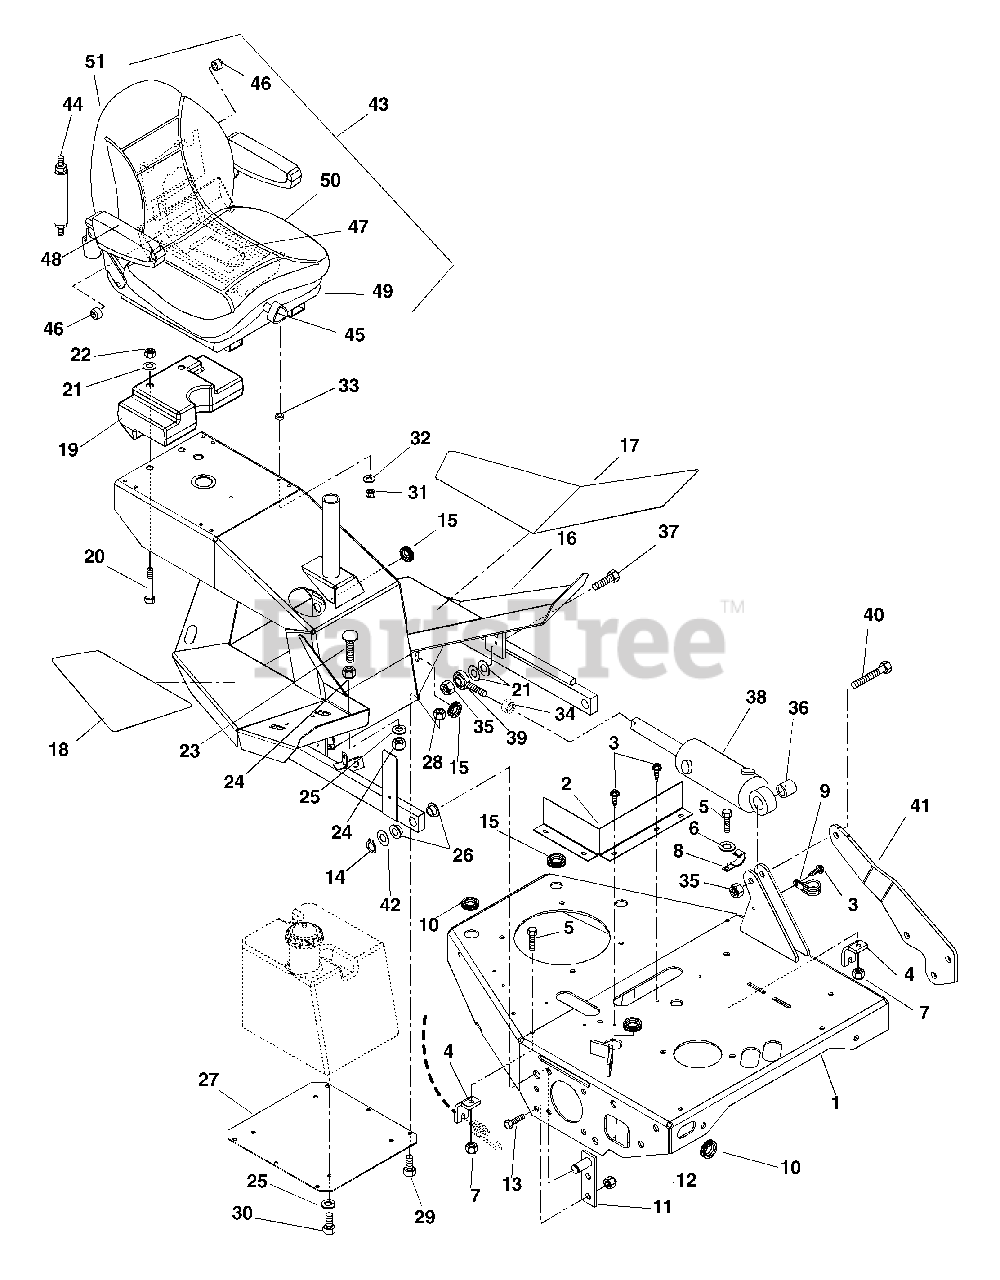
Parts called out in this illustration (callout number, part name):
1	Weldment, Frame
2	Heat Shield
3	Screw-Tapping .25-20 x .50 Hex Washer Head
4	Bracket, Cable
5	Bolt-Hex .31-18 x 1.00 Grade 5
6	Washer-Flat-Steel .344 x .688 x .065
7	Nut-Locking-Center .31-18
8	J-Clamp
9	Clamp, Steel 1.0
10	Grommet 1.25
11	Weldment, Pivot
12	Nut-Locking-Nylon .50-13
13	Bolt-Hex .50-13 x 1.50 Grade 5
14	Ring-Retaining-External .689 x .077
15	Grommet 75 x 1.06 x 1.38
16	Weldment, Sulky
17	Pad, Left Hand Floorboard
18	Pad, Right Hand Floorboard
19	Weight, Rear
20	Bolt-Hex .50-13 x 4.00 Grade 5
21	Washer-Flat-Steel .531 x 1.06 x .095
22	Nut-Locking-Nylon .50-13
23	Bolt-Round Head Square Neck .31-18 x 1.50 Grade 5
24	Nut-Hex .31-18
25	Washer-Locking .31 x .078
26	Bushing, Flange-Nylon .762 x 1.00 x .58 x 1.48
27	Plate, Bottom
28	Nut-Locking-Nylon .38-16
29	Bolt-Hex .38-16 x 1.00 Grade 5
30	Bolt-Hex .31-18 x .75 Grade 5
31	Nut-Locking-Nylon M8-1.25
32	Washer-Flat-Steel .38 x .875 x .083
33	Bushing-Sleeve .377 x .624 x .235
34	Nut-Jam .50-20 Grade 2
35	Nut-Locking-Nylon .50-13
36	Bushing, .516 x 1.00 x 1.05
37	Bolt-Hex .50-13 x 2.25 Grade 5
38	Cylinder, Platform Lift
39	Assembly-Rod End Right Hand
40	Bolt-Hex .50-13 x 3.00 Grade 5
41	Support, Cylinder Brace
42	Washer-Hardened-Thrust .758 x 1.23 x .031
43	Seat-Suspension
44	Kit-Damper with Hardware
45	Kit-Knob (1 per bag)
46	Kit-Roller (4 per bag)
47	Kit-Spring Cable (1 per bag)
48	Kit-Arm Pad (1 per bag)
49	Kit-Adjuster (1 per carton)
50	Kit-Cushion (1 per carton)
51	Kit-Seatback
